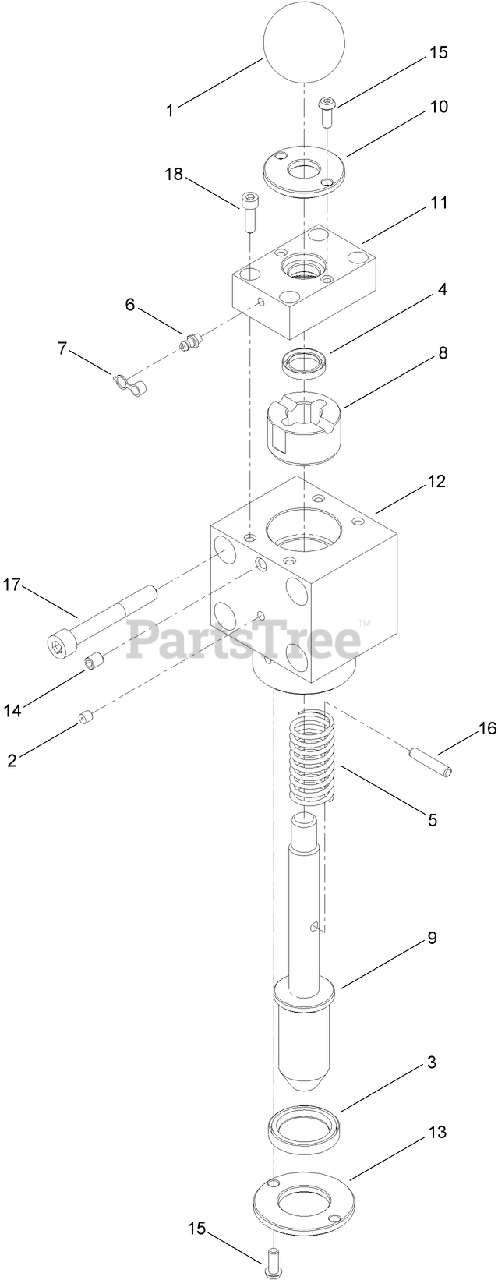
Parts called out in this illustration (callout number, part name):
1	KNOB-BALL
3	SEAL-LIP
4	SEAL-LIP
5	SPRING-COMPRESSION
6	FITTING-GREASE
7	CAP-PLUG
8	BUSHING-BRAKE, PARKING
9	PISTON-BRAKE PARKING
10	CAP-UPPER, BRAKE PARKING
11	HOUSING-UPPER, BRAKE PARKING
12	HOUSING-LOWER, BRAKE PARKING
13	CAP-LOWER, BRAKE PARKING
14	SCREW-HSH, SET
15	SCREW-HSBH
16	PIN-DOWEL
17	SCREW-HSH
18	SCREW-HSH
